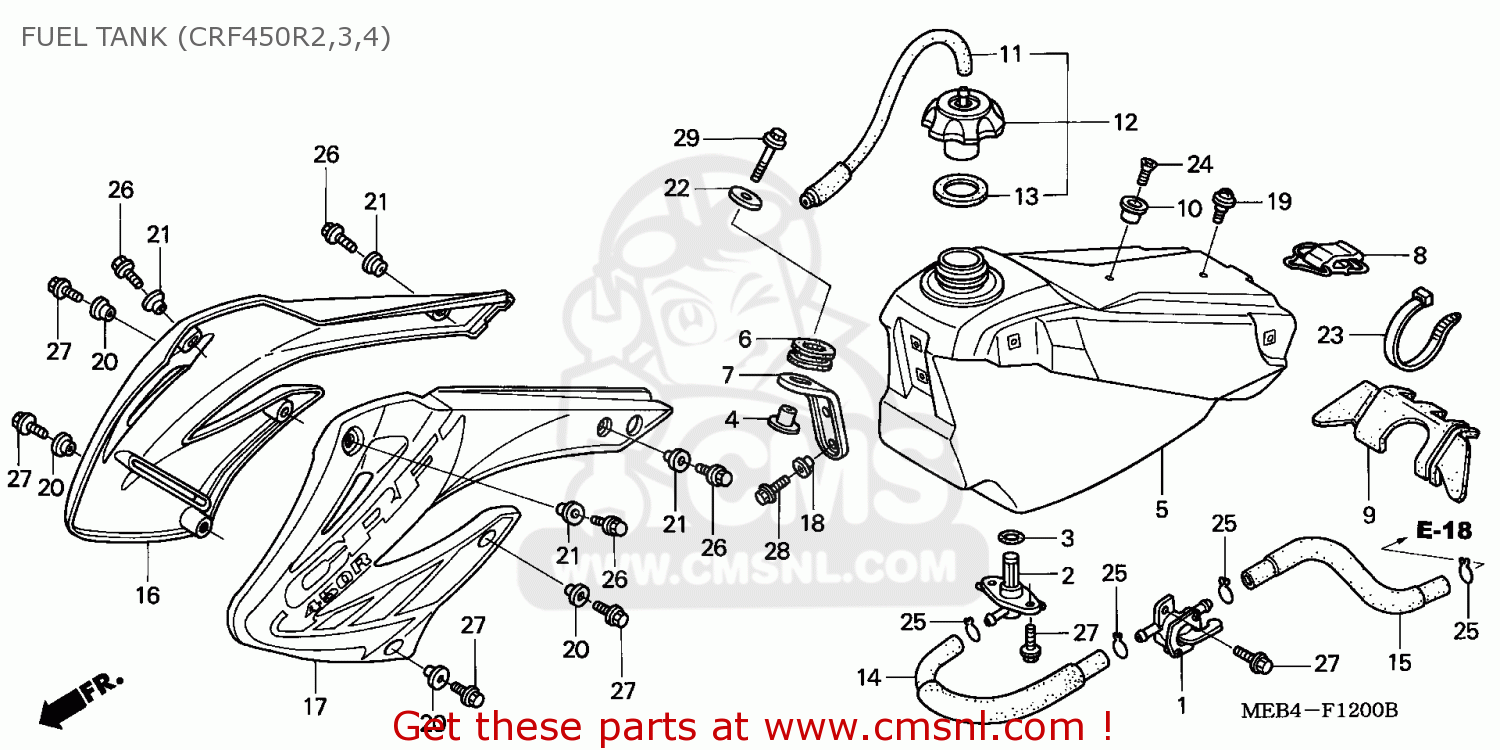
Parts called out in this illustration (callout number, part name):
1	COCK ASSY,FUEL
2	JOINT ASSY,FUEL
3	O-RING,11.8X3.55
4	COLLAR,TANK SET 6
5	TANK COMP,FUEL
6	RUBBER,TANK FRONT
7	STAY,FR.TANK
8	BAND,TANK REAR
9	RUBBER,TANK MT.
10	COLLAR,SEAT FR
11	TUBE COMP,FUELCAP
12	CAP ASSY,FUEL TAN
13	PACKING,FUEL CAP
14	TUBE,FUEL
15	TUBE,B FUEL
16	SHROUD SET, R. RADIA
17	SHROUD SET, L. RADIA
18	COLLAR,NUMBER BKT
19	SCREW,PAN,6X14
20	COLLAR,A
21	COLLAR,MIDDLE COV
22	WASHER,FENDER MT.
23	TY-RAP,CABLE TIE
24	SCREW FLAT 6X16
25	CLIP B12,TUBE
26	BOLT,FLANGE,6X12
27	BOLT,FLANGE,SH,6X16
28	BOLT,FLANGE,SH 6X18
29	BOLT,FLANGE,6X35
